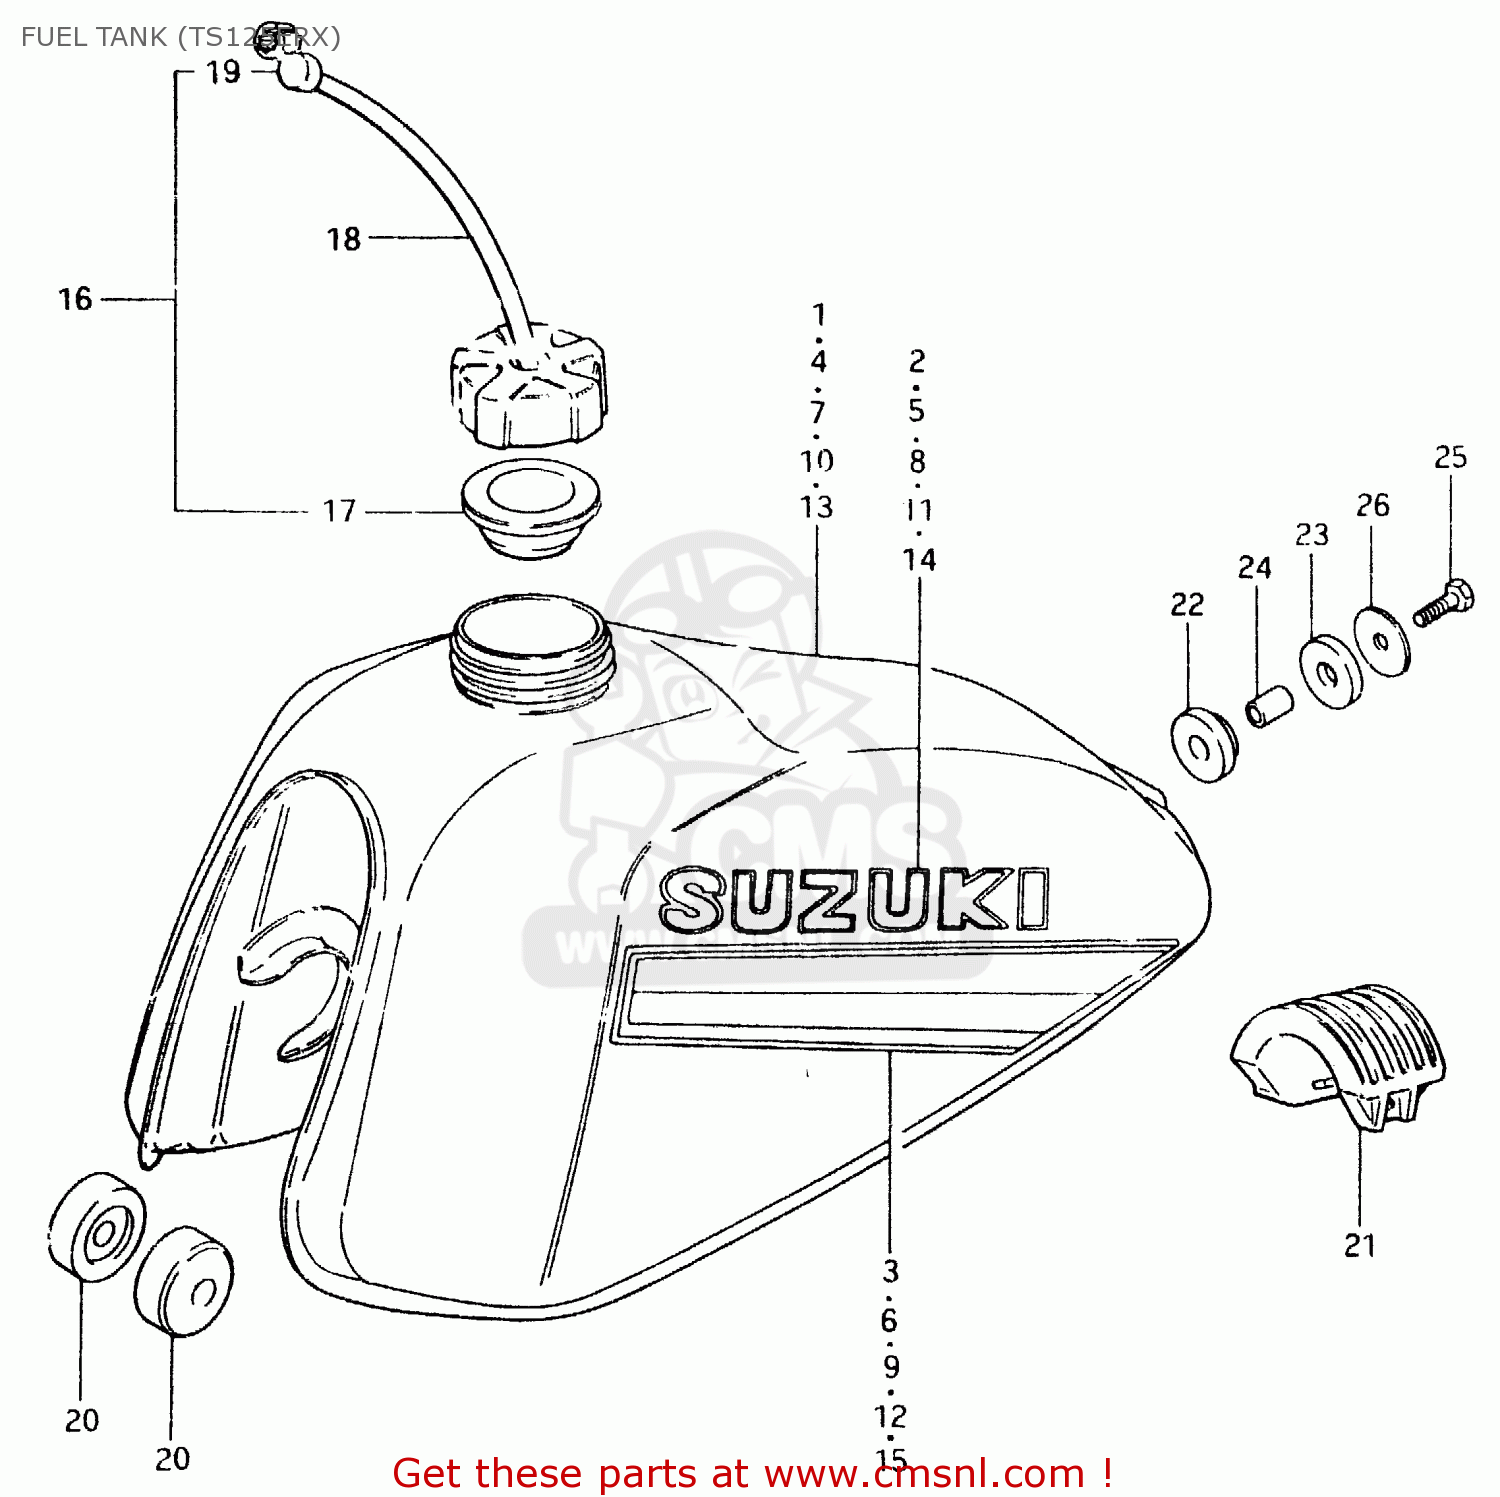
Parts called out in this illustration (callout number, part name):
1	TANK, FUEL (BLUE)
2	EMBLEM
3	TAPE SET
4	TANK, FUEL (YELLOE)
5	EMBLEM(BLACK)
6	TAPE SET
7	TANK, FUEL (RED)
8	EMBLEM
9	TAPE SET
10	TANK, FUEL (WHITE)
11	EMBLEM(BLACK)
12	TAPE SET
13	TANK, FUEL (BLACK)
14	EMBLEM
15	TAPE SET
16	CAP,FUEL TANK
17	GASKET,FUEL TANK CAP (NAS)
18	HOSE
19	CLAMP,FUEL TANK BREATHER HOSE
20	CUSHION
21	CUSHION,FUEL TANK
22	CUSHION
23	CUSHION
24	SPACER(8.5X12X19)
25	BOLT (8X30)
26	WASHER (8.5X29X1.6)
